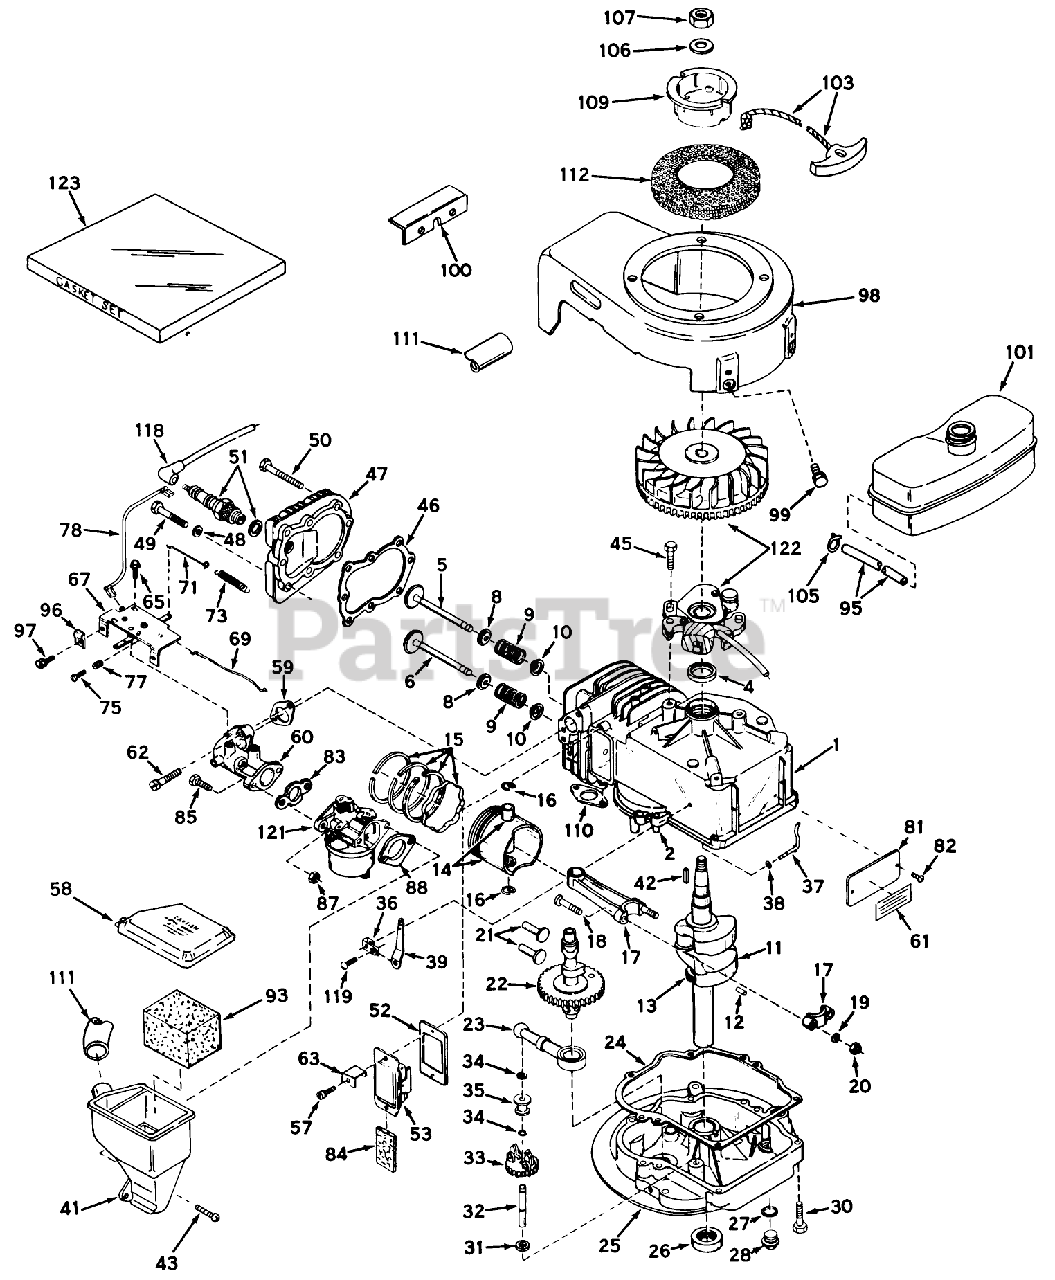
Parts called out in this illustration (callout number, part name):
1	Cylinder Assy. (Incl. Ref. 2 4)
2	Pin-Dowel
4	OIL SEAL
5	Valve, Intake (Incl. Ref. #38, 39 40) (Std.)
5	Valve, Intake(1/32"overs.)(Incl. Ref. 8, 9 10)
6	Valve, Exhaust (Standard)(Incl. Ref. 8, 9 10)
6	Valve, Exhaust (1/32" Overs.(Incl. Ref. 8, 9 10)
8	Cap-Upper Valve Spring
9	Spring-Valve
10	Cap-Valve, Spring
11	Crankshaft Assy. (Incl. Ref. 12 13)
12	Pin, Groove
13	Gear, Crankshaft
14	Piston Pin Assy. (Incl. 2 of No. 16)(Standard)
14	Piston Pin Assy. (Incl. 2 of No. 16)(.010 oversize)
14	53020 ADN. TO 28594
15	Piston Ring Set Std.
15	Piston Ring Set .010 O.S.
15	Piston Ring Set .020 O.S.
16	Ring-Retaining, Piston Pin
17	Rod Assy., Connecting (Incl. Ref. #17)
18	Bolt, Connecting
19	Washer
20	LOCKNUT
21	Lifter-Valve
22	Camshaft
23	Oil Pump ASM
24	Gasket, Mounting
25	Flange Assy., Mounting (Incl. Ref. 26, 27, 28 32)
26	Seal Oil
27	Gasket-Oil Drain
28	Plug Oil Drain
30	Screw (1/4-20 x 1-1/4)
31	Washer-Flat
32	Shaft-Governor
33	Governor Gear ASM
34	Ring-Retaining
35	Spool-Governor
36	Clamp-Lever, Governor
37	Rod, Governor (Incl. No. 36)
38	Washer-Flat
39	Governor Lever
41	Body, Air Cleaner
42	Key Flywheel
43	Screw, Fil. Hd. Sems
45	Screw
46	Gasket-Cylinder Head
47	CYLINDER HEAD
48	Washer
49	Screw
50	Screw Hex Hd. Cap
51	SPARK PLUG
52	Gasket Breather
53	Breather Assembly (Incl. Nos. 52 84)
57	Screw
58	Cover, Air Cleaner
59	Gasket, Intake
60	Pipe, Intake
61	480B GIL SNWTHWR O/
62	Screw, Fil. Hd. Sems
63	Retainer Clip
65	Screw (10-24 x 9/16)
67	Control Assy., Speed
69	Link, Throttle to Governor
71	Link-Governor
73	Spring, Governor
75	Screw
77	Spring-Compression
78	Wire, Ground
81	IDENTIFICATION PLATE
82	Stud
83	Gasket
84	Element-Breather
87	Nut and Lock Washer (1/4-28)
88	Gasket-Air Cleaner
93	Element, Air Cleaner
95	Line-Fuel (8.62)
96	Conduit
97	Screw (10-32 x 3/8)
98	Housing, Blower
99	Screw (1/4-20x19/32)
100	Bracket, Shroud
101	Tank, Fuel
103	Rope Assy., Starter
105	Clamp-Line, Fuel
106	Washer
107	Hex Nut
109	Pulley Starter
110	Gasket Exhaust
111	Tube, Air Cleaner
112	Screen, Air
118	Cover-Spark Plug
119	Screw
121	Carburetor
122	Magneto
123	Gasket Set (Incl. Items Marked *)
